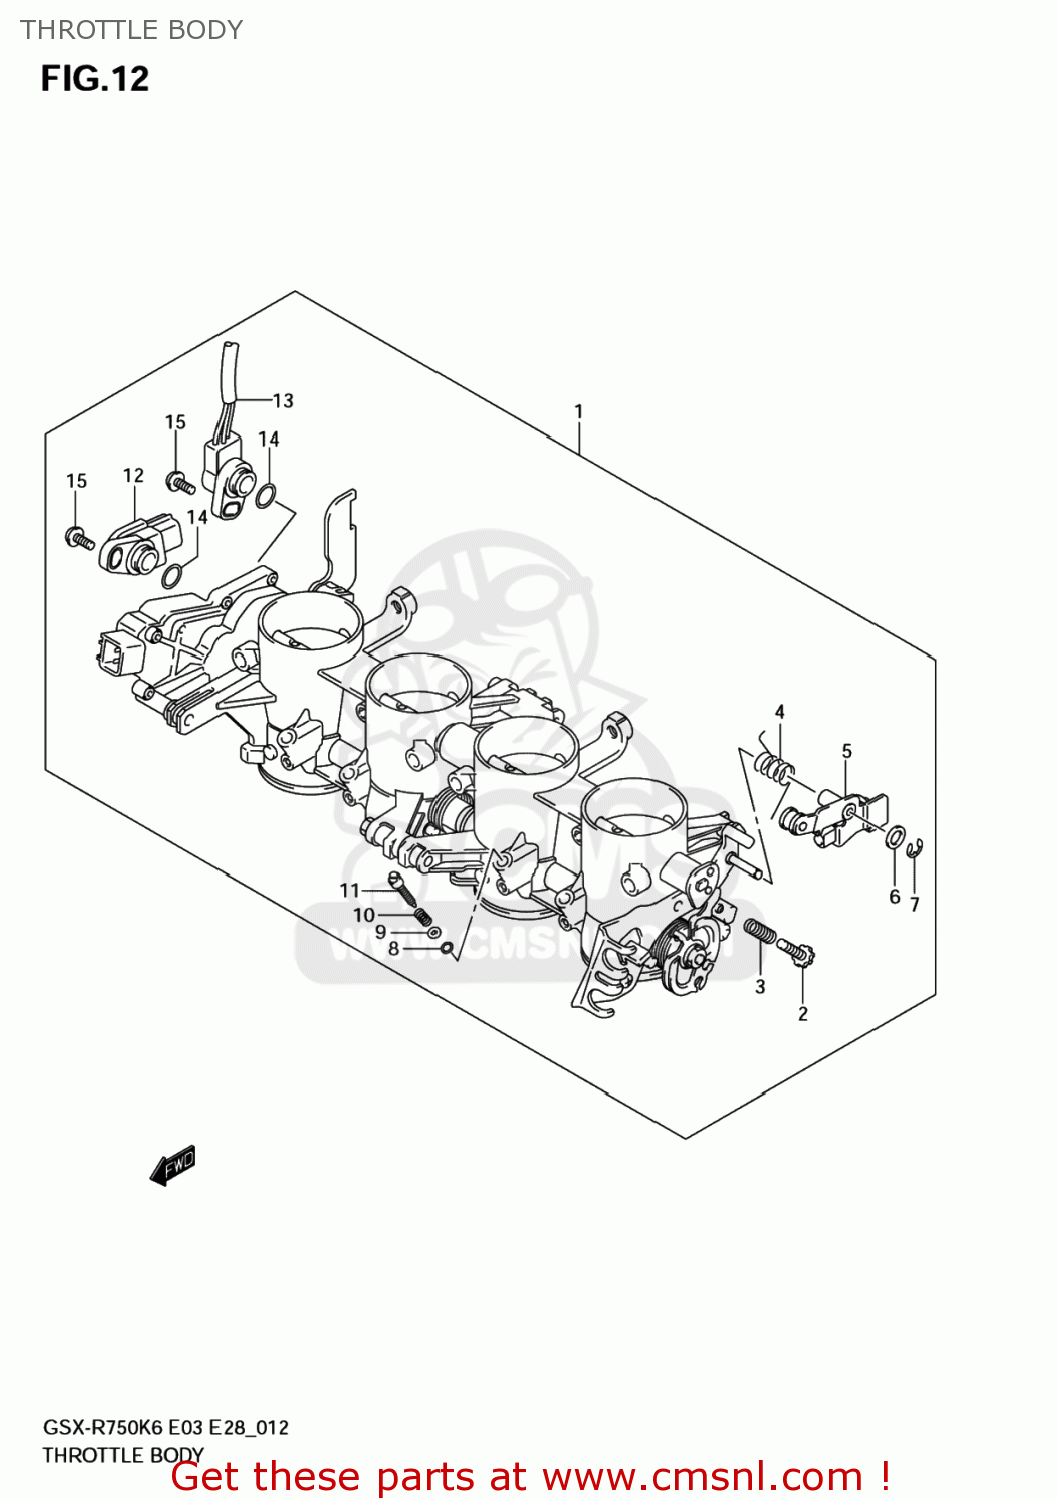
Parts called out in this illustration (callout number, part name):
1	BODY ASSY,THROTTLE
2	SCREW,ADJUST
3	SPRING
4	SPRING,TORSION
5	LEVER ASSY
6	PACKING (NAS)
7	E RING
8	O RING,PILOT AIR SCREW
9	WASHER
10	SPRING,THROTTLE SCREW
11	SCREW
12	SENSOR ASSY
13	SENSOR ASSY,TH
14	O RING
15	SCREW
